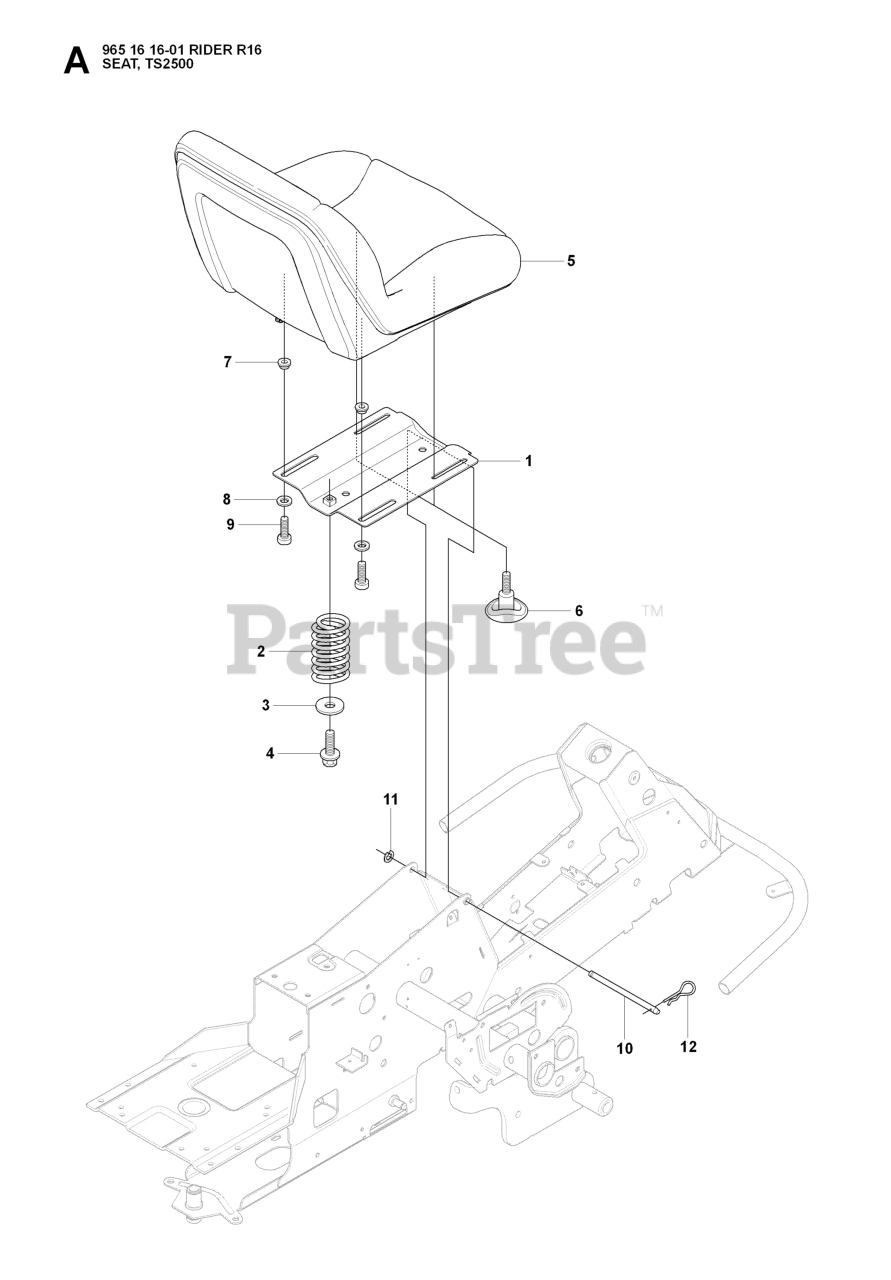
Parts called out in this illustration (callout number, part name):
1	SEAT BRACKET
2	SEAT SPRING
4	Screw M10x25
5	SEAT
6	ADJUSTING KNOB
11	RETAINING RING SGA 10
